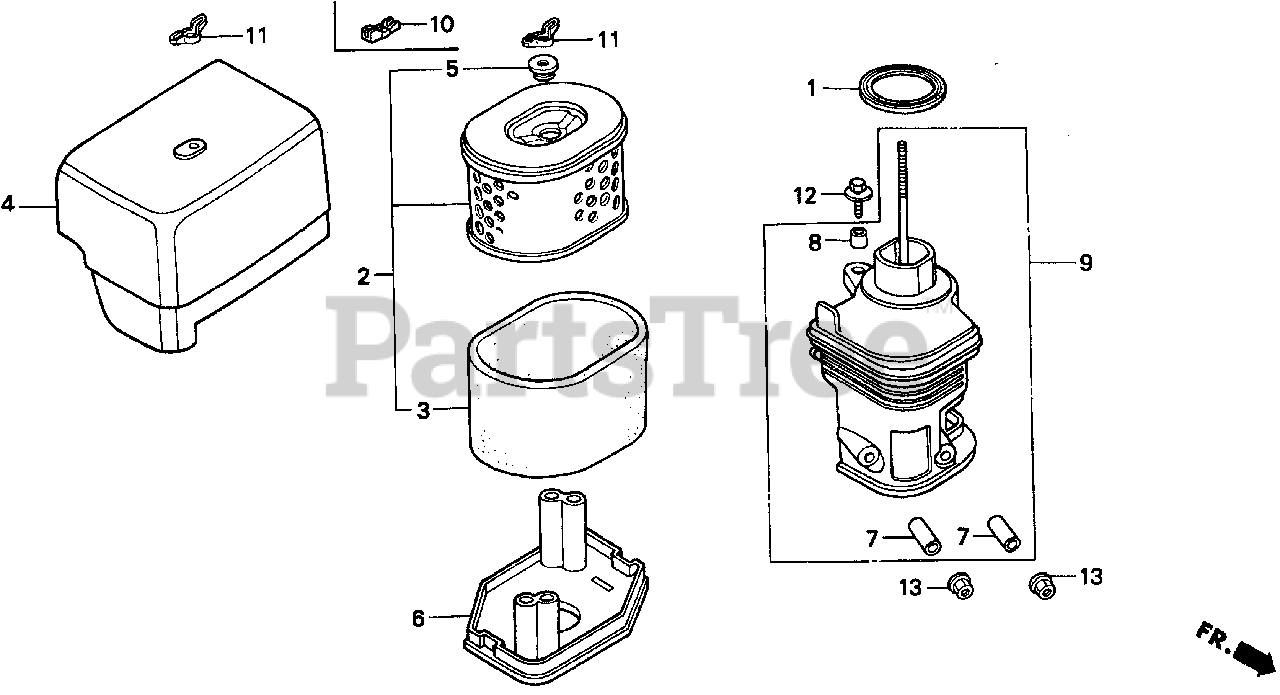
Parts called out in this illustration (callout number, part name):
1	GASKET, ELBOW
2	ELEMENT, AIR CLEANER
3	FILTER (OUTER)
4	COVER, AIR CLEANER
5	GROMMET, AIR CLEANER
6	NOSE, MUFFLER
7	COLLAR, AIR CLEANER
8	COLLAR B, AIR CLEANER
9	ELBOW, AIR CLEANER
11	WINGNUT, TOOL BOX SETTING
12	BOLT-WASHER (6X20)
13	NUT, FLANGE (6MM)
